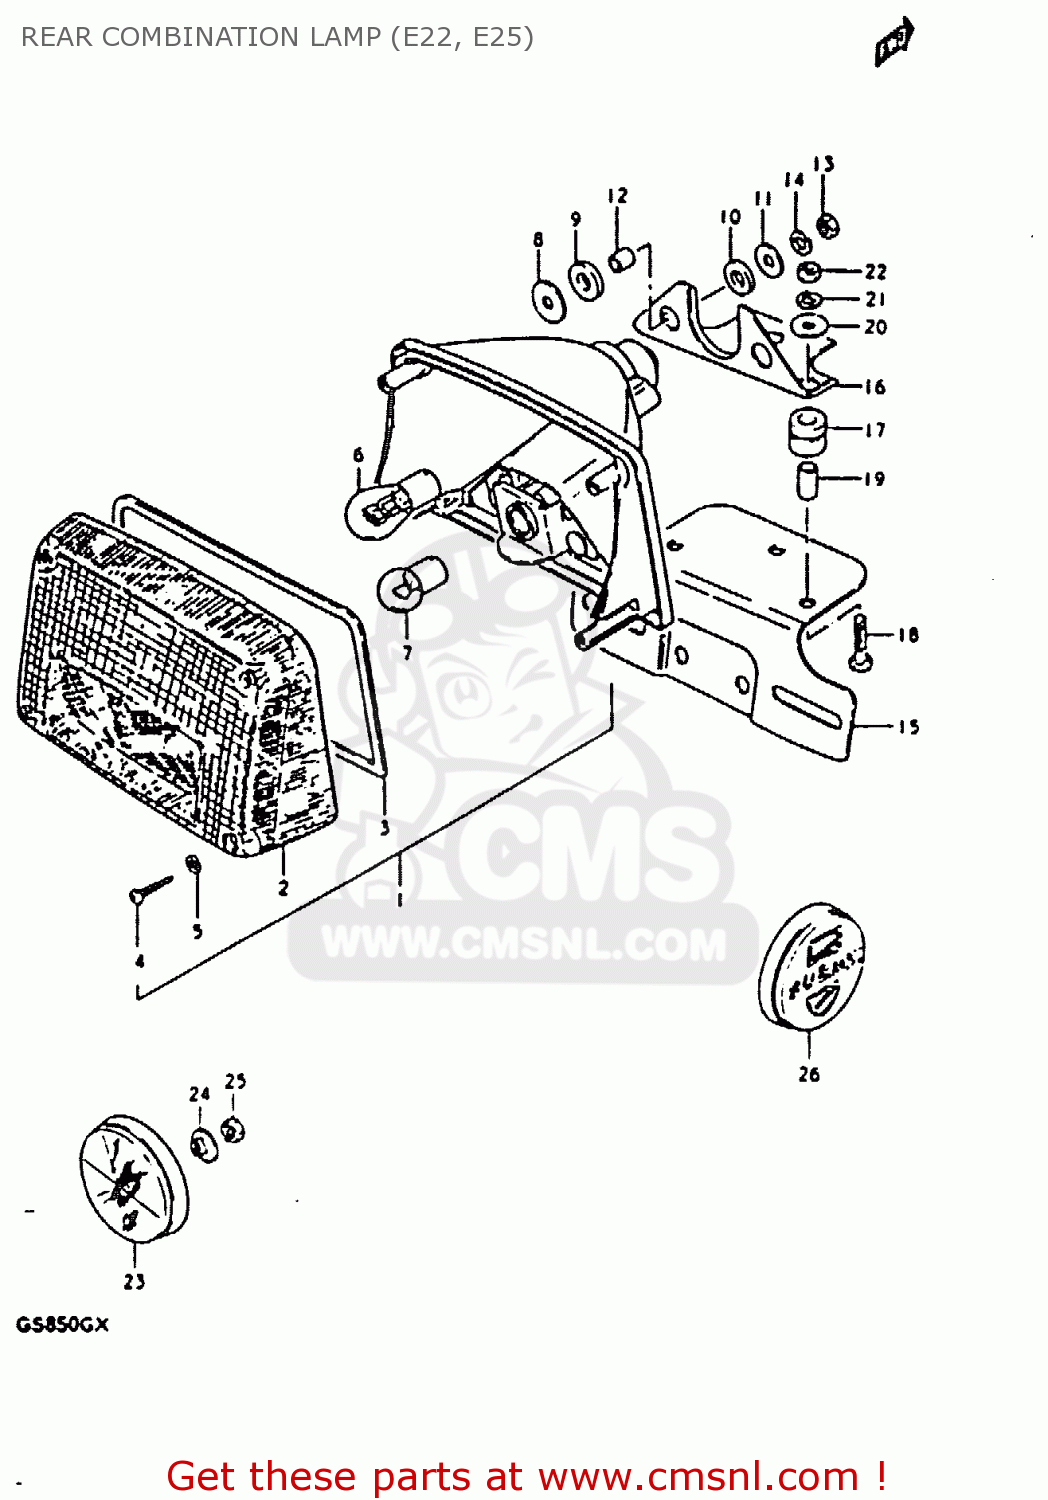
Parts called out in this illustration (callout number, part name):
1	LAMP, REAR COMBINATION
2	LENS
3	GASKET (NAS)
4	BOLT
5	GASKET (NAS)
6	BULB(12V21/5W)
7	BULB(12V10W,TOKAI DENSO)
8	WASHER
9	CUSHION
10	CUSHION
11	WASHER(6,5X22X1.6)
12	SPACER(6.1X9X7.5)
13	NUT
14	LOCK WASHER
15	BRACKET, LICENCE PLATE
16	BRACKET,LICENSE PLATE
17	CUSHION, BRACKET
18	BOLT
19	SPACER (6.4X9X15.5)
20	WASHER
21	LOCK WASHER
22	NUT
23	REFLEX REFLECTOR,RR
24	SPACER
25	NUT
26	EMBLEM, REAR SIDE
